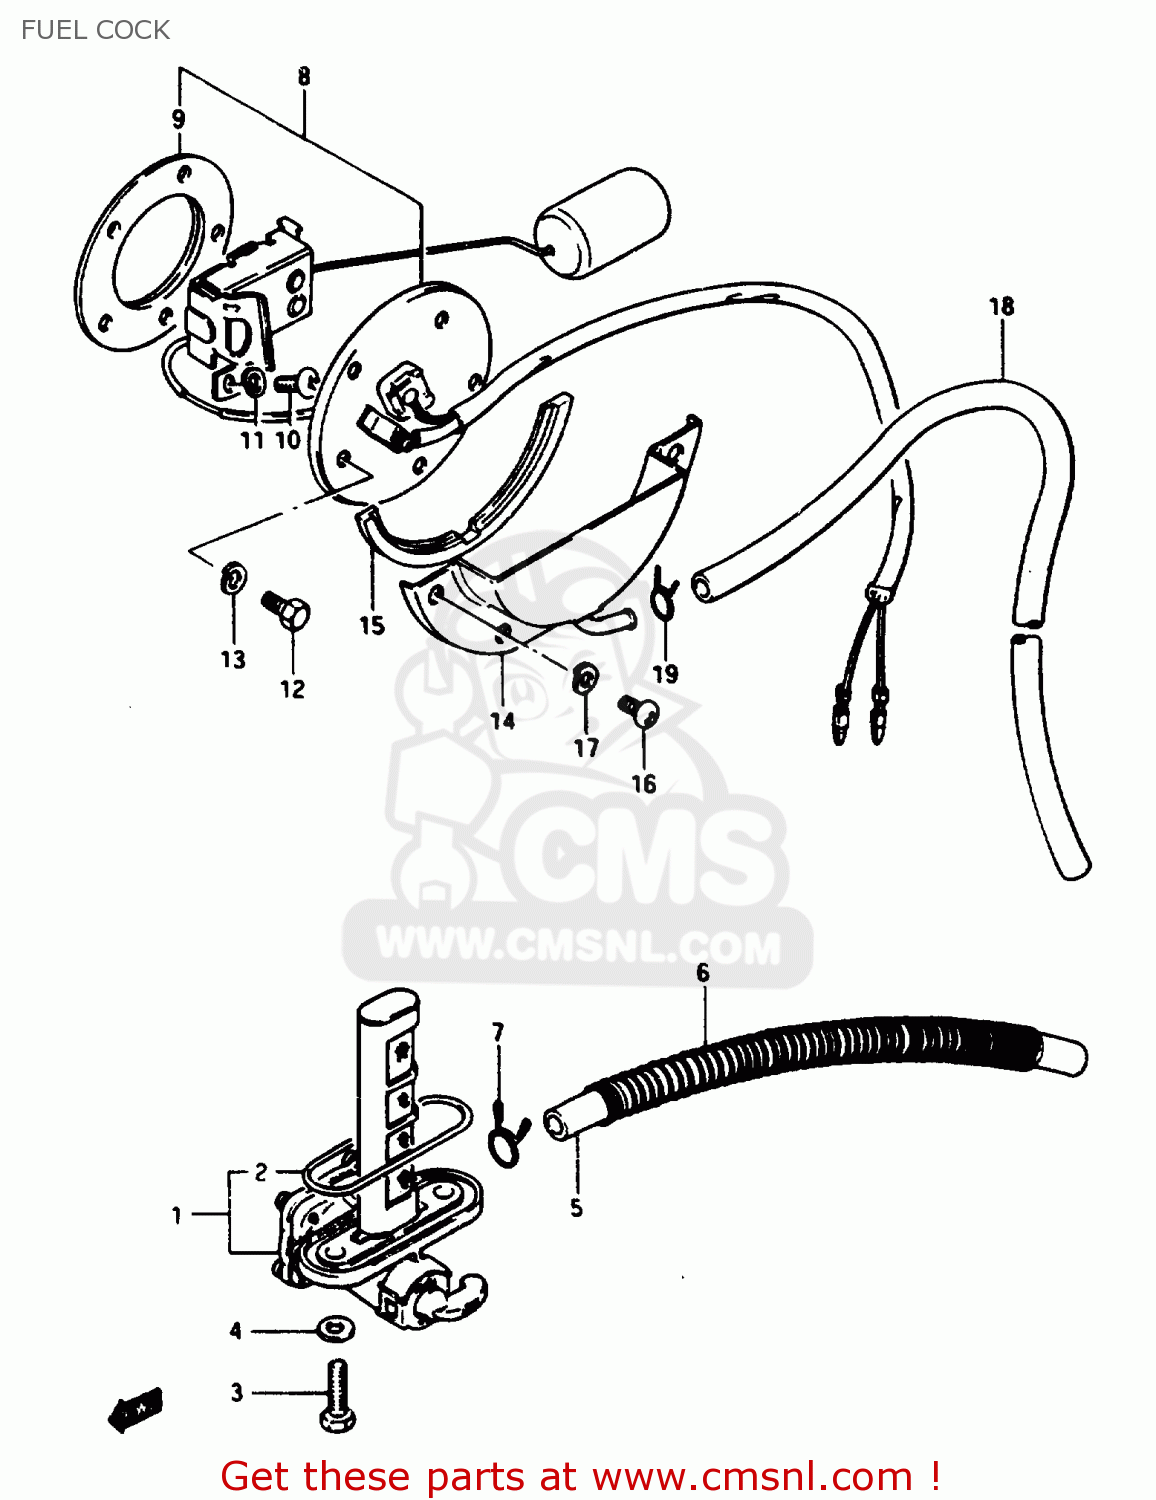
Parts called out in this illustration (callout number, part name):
1	COCK ASSY,FUEL
2	O RING
3	BOLT(6X20)
4	GASKET
5	HOSE
6	SPRING
7	CLIP
8	GAUGE ASSEMBLY,FUEL LEVEL
9	GASKET,FUEL LEVEL GAUGE (NAS)
10	SCREW 5X10
11	LOCK WASHER
12	BOLT
13	LOCK WASHER
14	PLATE,FUEL DRAIN
15	GASKET (NAS)
16	SCREW
17	LOCK WASHER
18	HOSE,FUEL
19	CLIP
